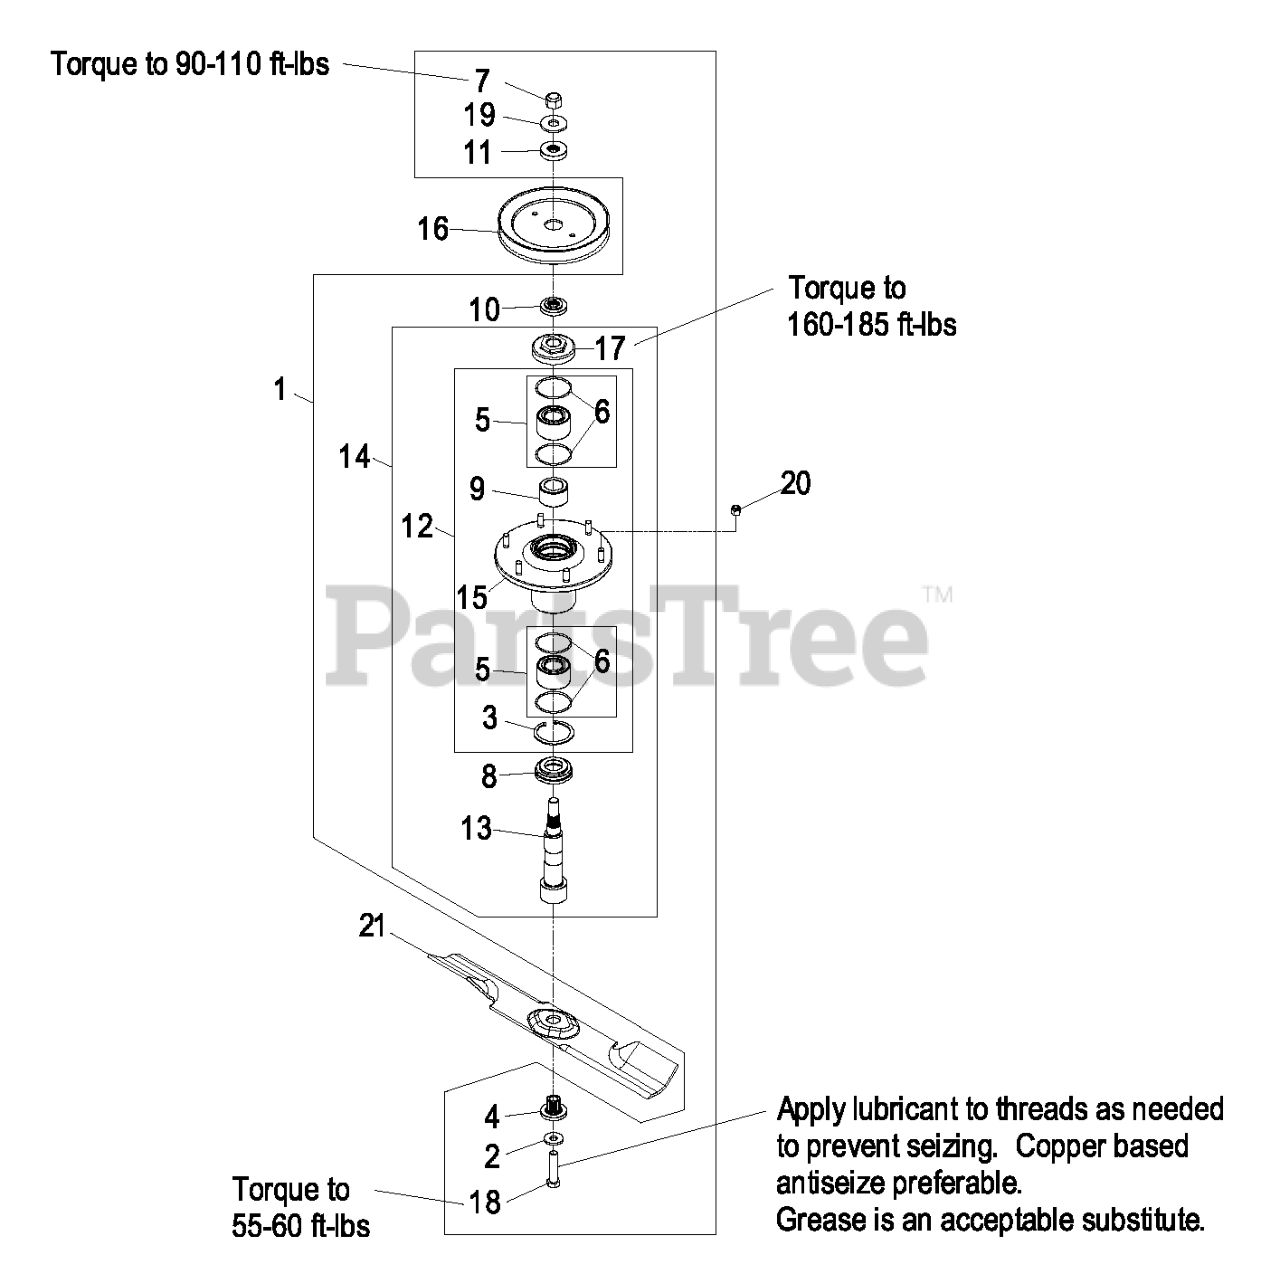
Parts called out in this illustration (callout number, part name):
1	ASM, CUTTER HSG W/MNT HRD
2	WASHER-SPRING
3	RING-RETAINING
4	BUSHING,SPLINED
5	ASM, BEARING W/ORINGS
7	NUT-LOCK NI
8	GUARD,BOTTOM
9	SPACER,BEARING
10	SPACER,SPLINED STEPPED
11	SPACER,SPLINED
12	ASM,CUTTER HOUSING
15	ASM,HOUSING W/STUDS
16	SHEAVE, BLADE DRIVE 6.13
18	SCREW-HH
19	WASHER-FLAT
20	NUT-LOCK, NI
